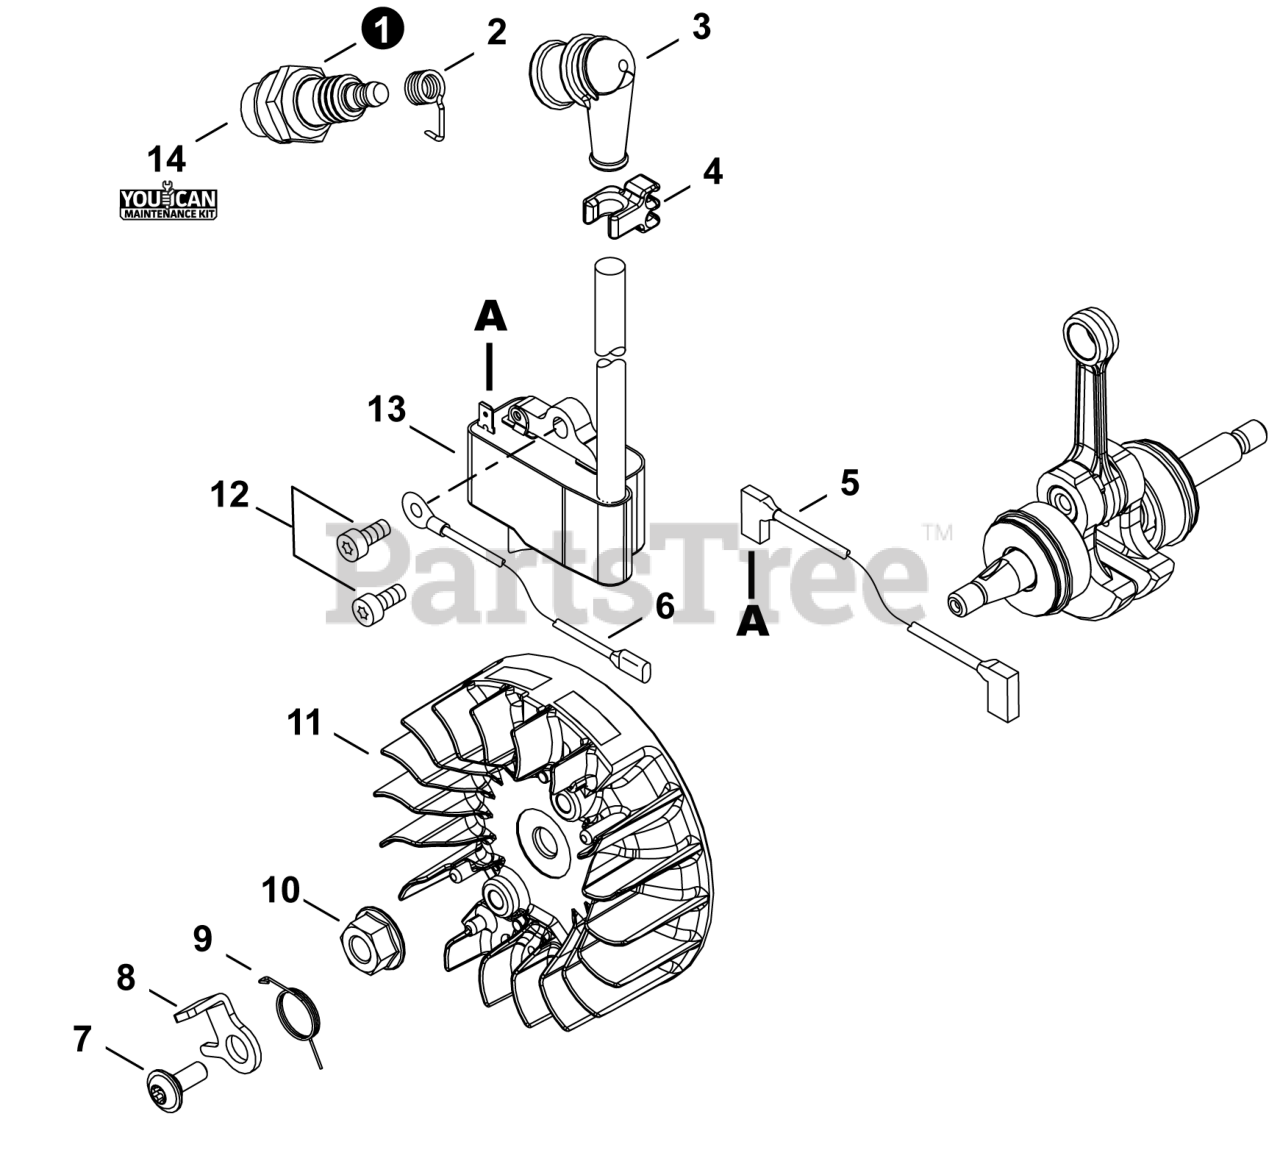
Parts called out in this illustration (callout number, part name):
1	SPARK PLUG - BPMR8Y
2	TERMINAL, SPARK PLUG
3	CAP, SPARK PLUG
5	LEAD - IGNITION L= 160
6	LEAD - GROUND L= 120
7	BOLT 5x11
9	SPRING, TORSION
10	NUT, FLANGE M8
11	FLYWHEEL
12	BOLT, TORX 5x16
13	COIL, IGNITION
14	TUNE-UP KIT - YOUCANT
